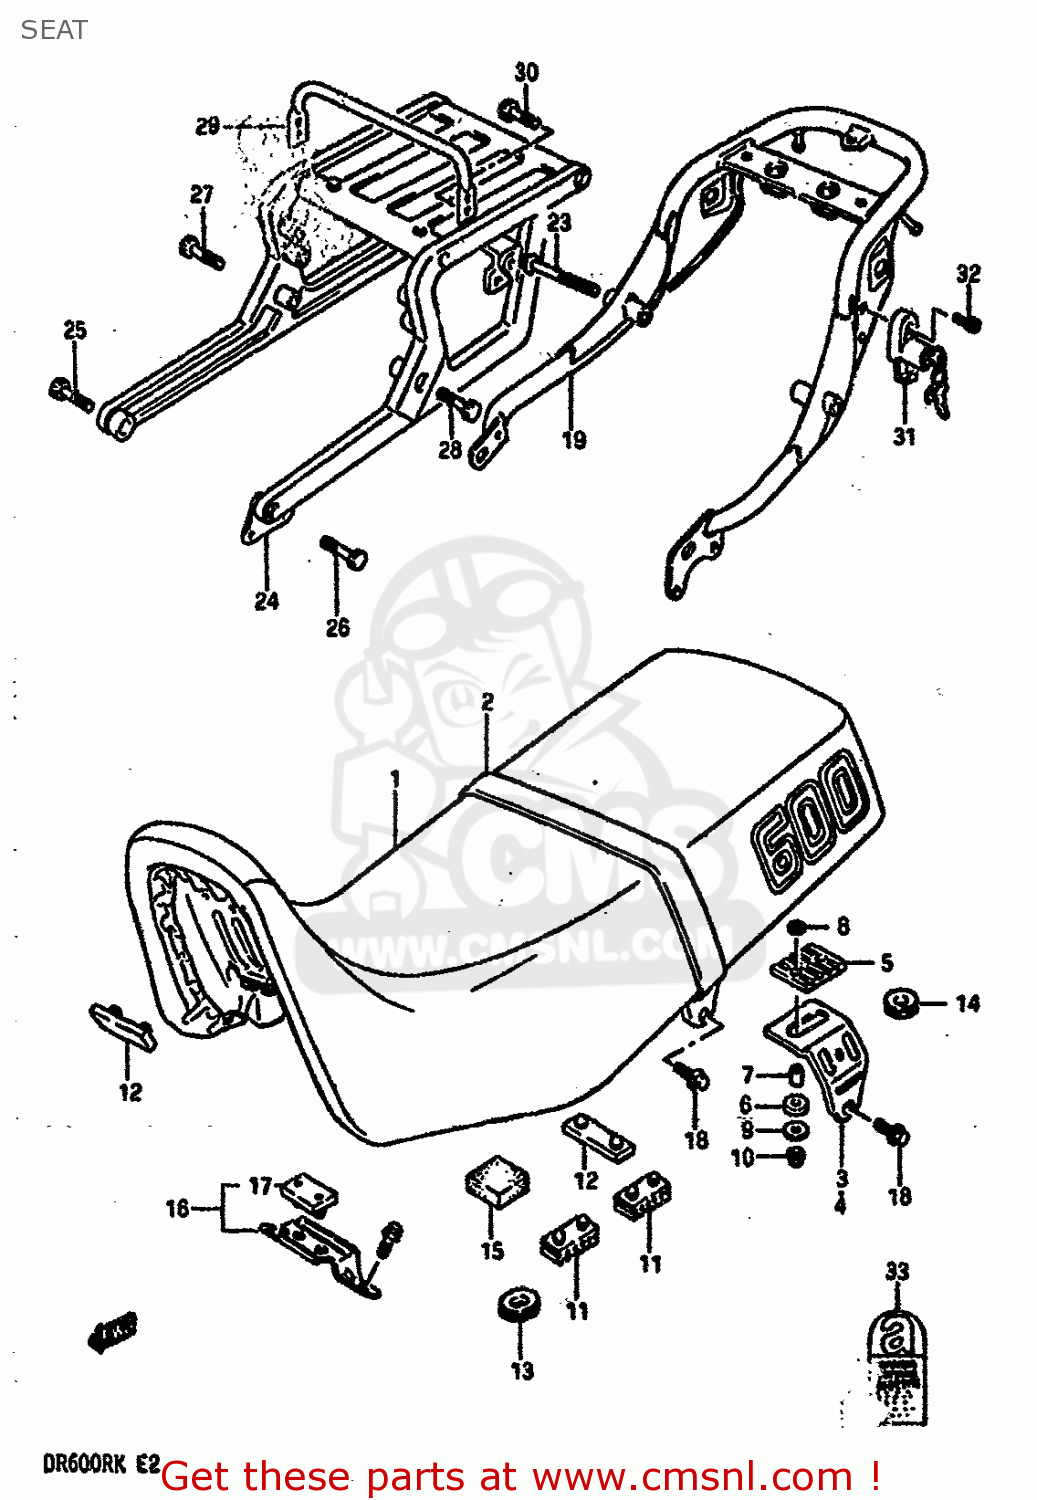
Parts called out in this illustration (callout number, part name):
1	SEAT SET
2	BAND,SEAT (WHITE)
3	BRACKET,SEAT,RIGHT
4	BRACKET,SEAT,LEFT
5	CUSHION,SEAT FR
6	CUSHION,FR PLATE
7	SPACER,SEAT SUPPORT
8	WASHER
9	WASHER, LOWER
10	NUT
11	CUSHION,SEAT(40X20X15)
12	CUSHION
13	CUSHION
14	CUSHION
15	CUSHION,TOOL(40X30X15)
16	PLATE ASSY,SEAT FR HOOK
17	CUSHION
18	BOLT, 8X1.25X1
19	CARRIER COMP,SUPPORT
20	BOLT
21	LOCK WASHER
22	WASHER
23	BOLT (8X70)
24	CARRIER ASSEMBLY,REAR
25	BOLT, FRONT RH
26	BOLT, FRONT LH
27	BOLT, REAR RH
28	BOLT ,8X50
29	TUBE, PILLION HANDLE
30	BOLT 8X16
31	LOCK SET
32	BOLT
33	LABEL,ASBESTOS WARNING
